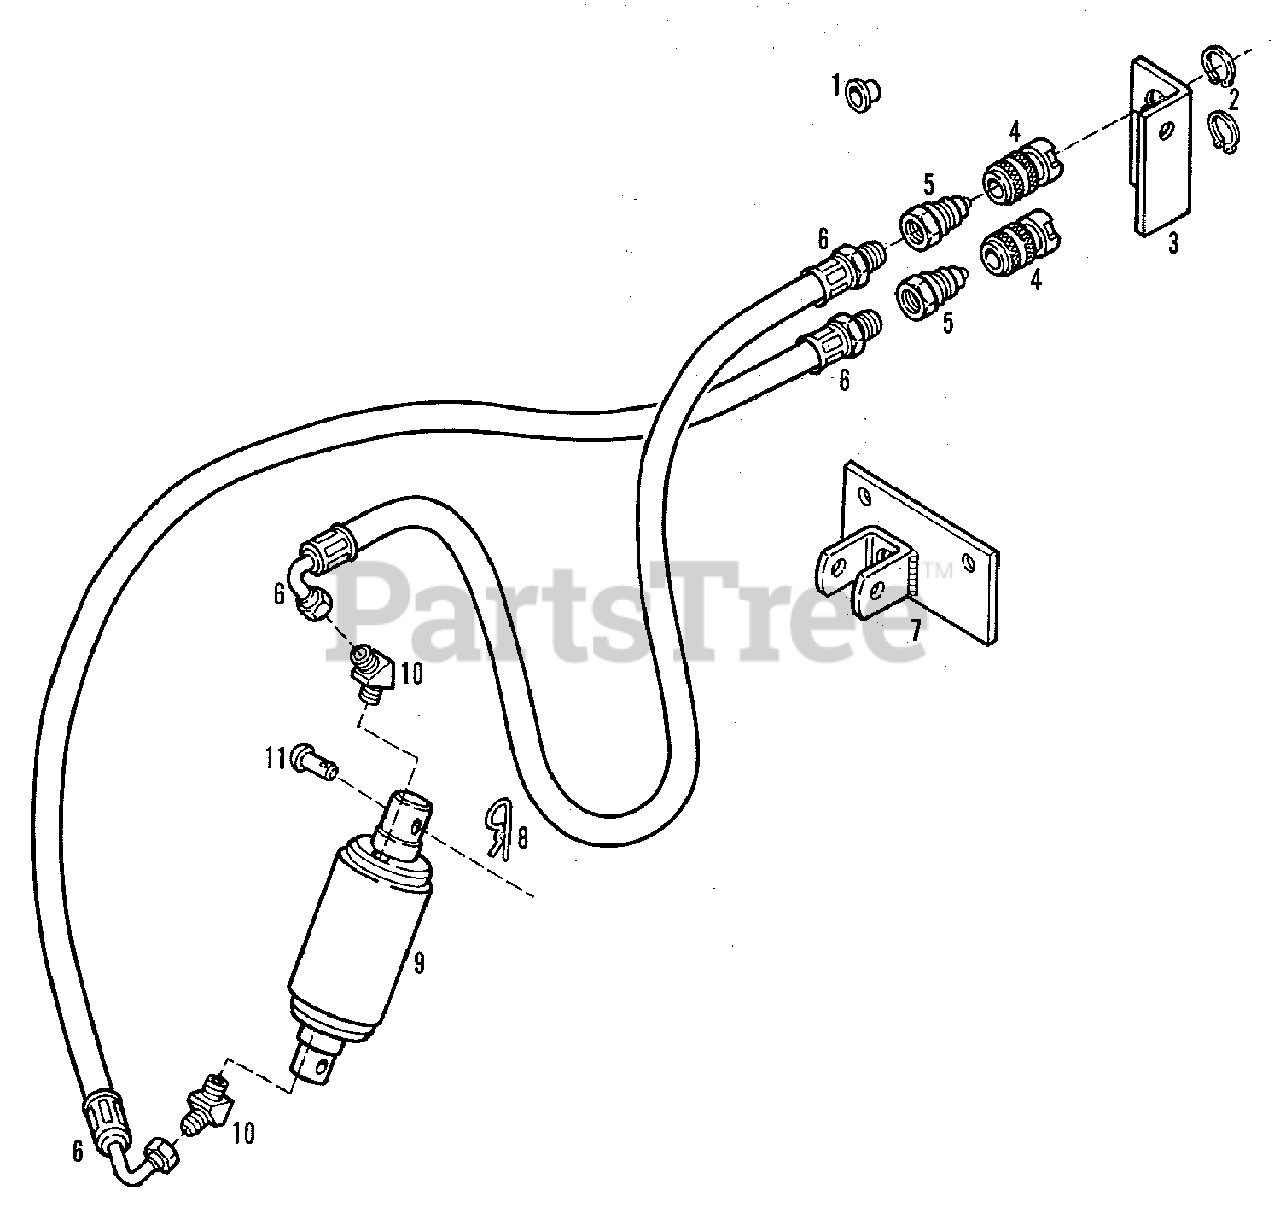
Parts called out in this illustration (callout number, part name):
1	PLUG, Plastic
2	RING, Retaining
3	PLATE, Mounting
3	CAPSCREW, M8 x 1-1/4 x 20
3	LOCKWASHER, 5/16
4	BODY ASSEMBLY
5	NOSE PIECE ASSEMBLY
6	HOSE ASSEMBLY
7	MOUNT ASSEMBLY, Cylinder
7	CAPSCREW, 1/2NC x 1-1/4
7	LOCKWASHER, 1/2
8	CLIP, Hairpin
9	CYLINDER ASSEMBLY
